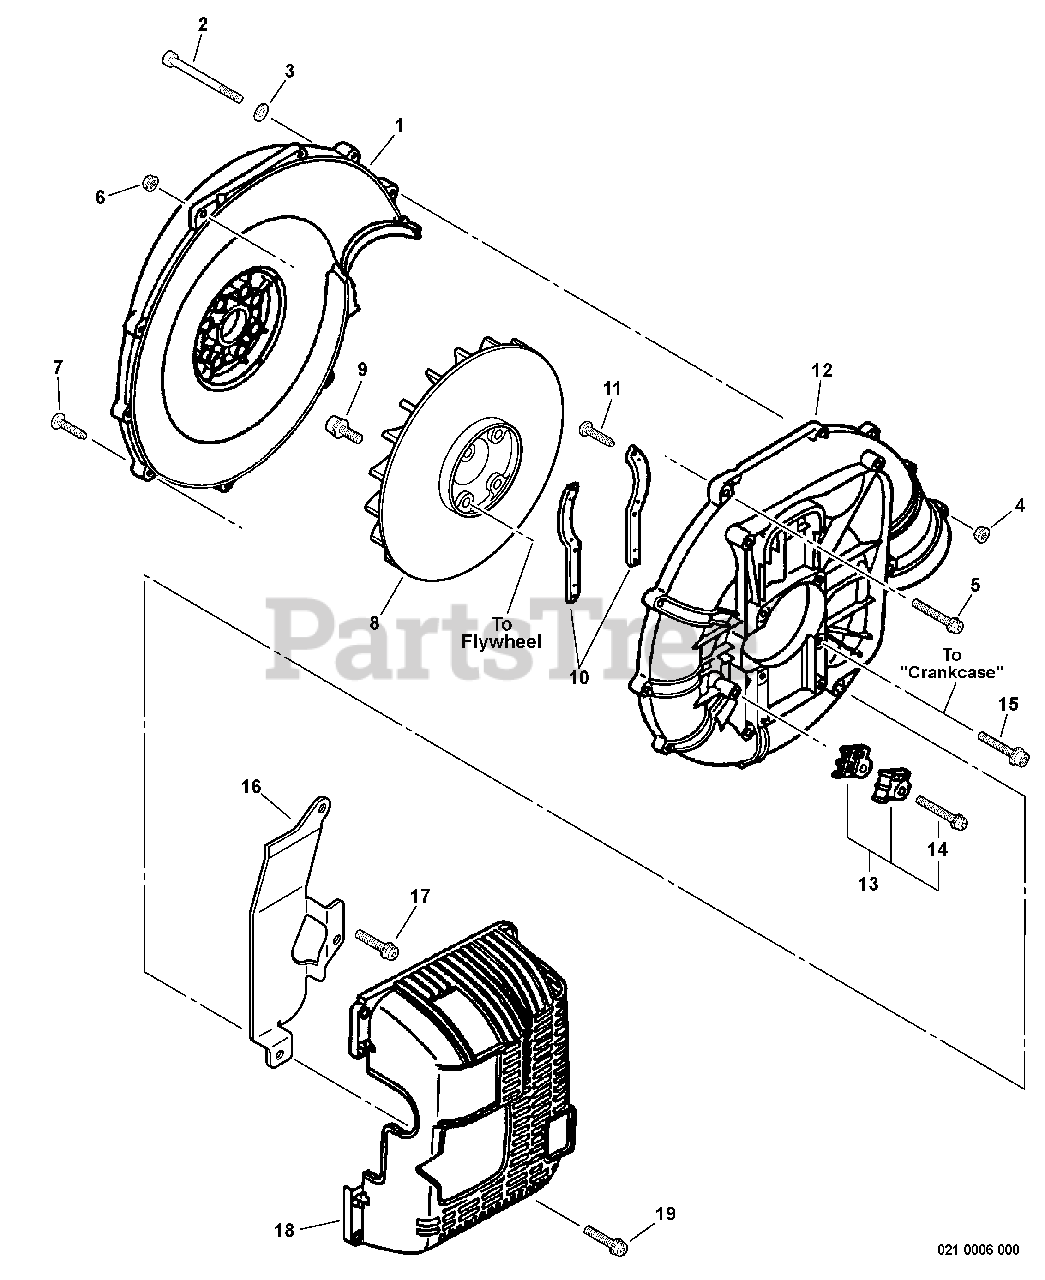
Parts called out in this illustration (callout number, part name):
1	COVER, FAN - INNER
2	BOLT 5×60
3	WASHER, FLAT 5.5×10×0.8
4	NUT, FLANGE M5
5	SCREW 5×40
6	NUT, FLANGE M5
7	SCREW 5×30
8	FAN
9	BOLT 5×20
10	BRACKET, ENGINE
11	SCREW TAPPING 3×12
12	COVER, FAN - OUTER
13	CABLE HOLDER KIT
14	SCREW 5×25
15	SCREW 5×32
16	INSULATOR
17	SCREW 5×10
18	COVER, ENGINE
19	SCREW 5×18
